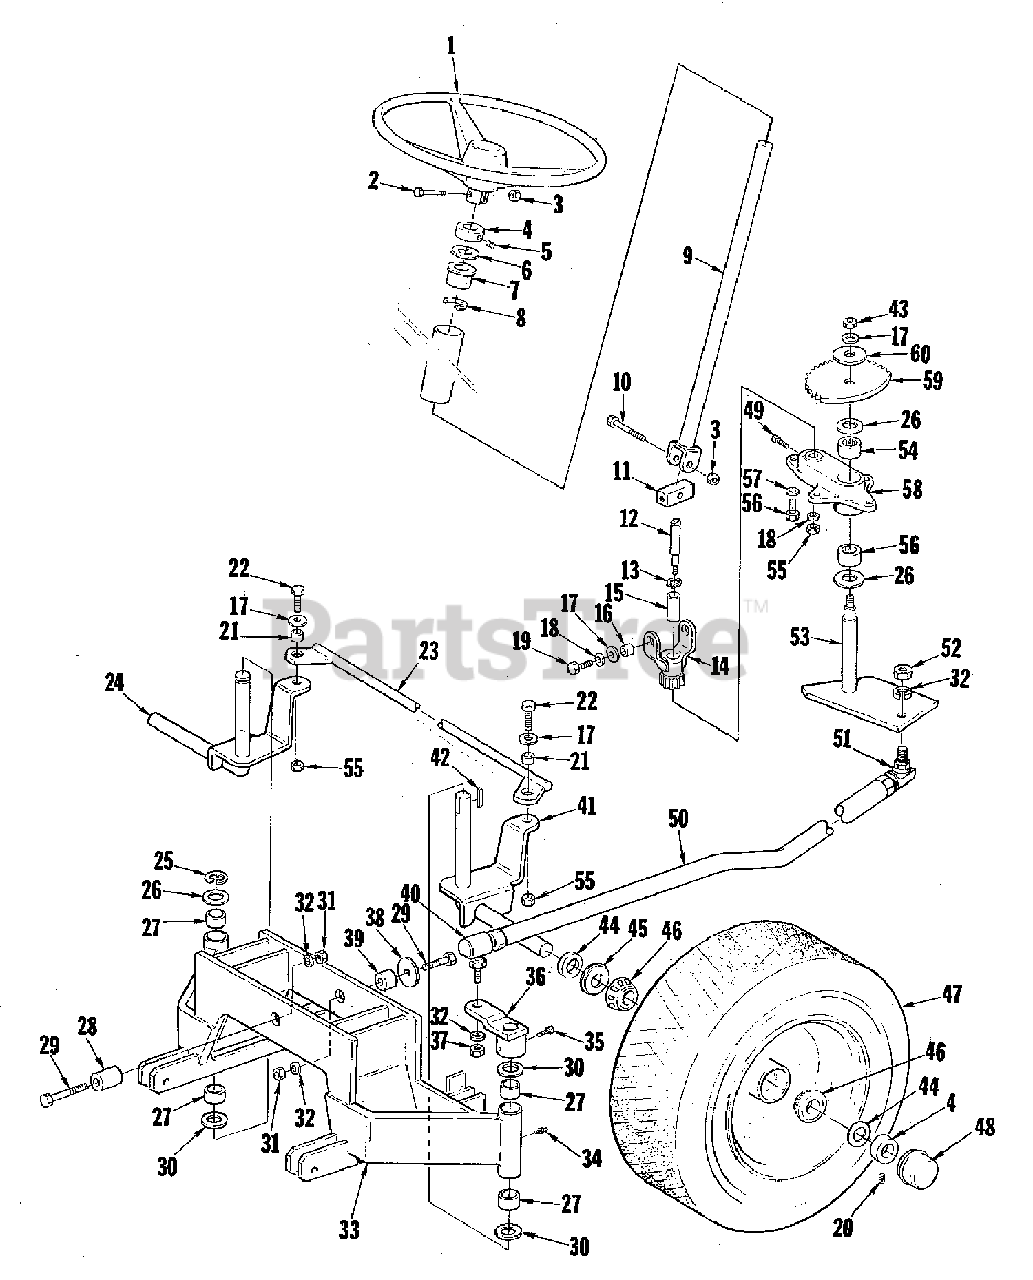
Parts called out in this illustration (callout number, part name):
1	WHEEL, Steering
2	SCREW, Hex head, Cap, 5/16-18 x 1-1/4
3	NUT, Hex Lock, 5/16-18
5	SETSCREW, 5/16-18 x 1/4
6	WASHER, Special
7	BUSHING, Steering
9	SHAFT ASSEMBLY, Steering
10	SCREW, Hex Head Cap, 5/16-18 x 1-1/2
11	PIN, Universal Joint
12	PIN, Eccentric
13	RING, Retainer
14	BUSHING ASSEMBLY
17	WASHER, Flat, 3/8
18	WASHER, Lock, 3/8
19	SCREW, Hex Head Cap, 3/8-16 x 3/4
20	SETSCREW, 5/16-18 x 5/16
22	SCREW, Cap, 3/8-16 x 1-1/4
24	SPINDLE ASSEMBLY, R.H.
25	RING, Retaining
29	SCREW, Hex Head Cap, 1/2-13 x 2
31	NUT, Hex Fin
32	WASHER, Lock, 1/2
33	AXLE ASSEMBLY, Front
34	FITTING, Lube, Straight
35	SETSCREW, Square Head, 5/16-18 x 1/2
36	ARM ASSEMBLY, Steering
37	NUT, Hex Jam, 1/2-20
38	WASHER, Flat
41	SPINDLE ASSEMBLY, L.H.
43	NUT, Hex Lock, 7/16
46	CONE, Bearing
47	WHEEL & TIRE ASSEMBLY, Front
53	ARM ASSEMBLY, Steering
54	NEEDLE BEARING
55	NUT, Hex Lock, 3/8-16
56	SCREW, Hex Head Cap, 5/16-18 x 5/8
57	WASHER, Lock, 5/16
58	BRACKET, Steering
59	GEAR, Steering
60	WASHER, Arbor
